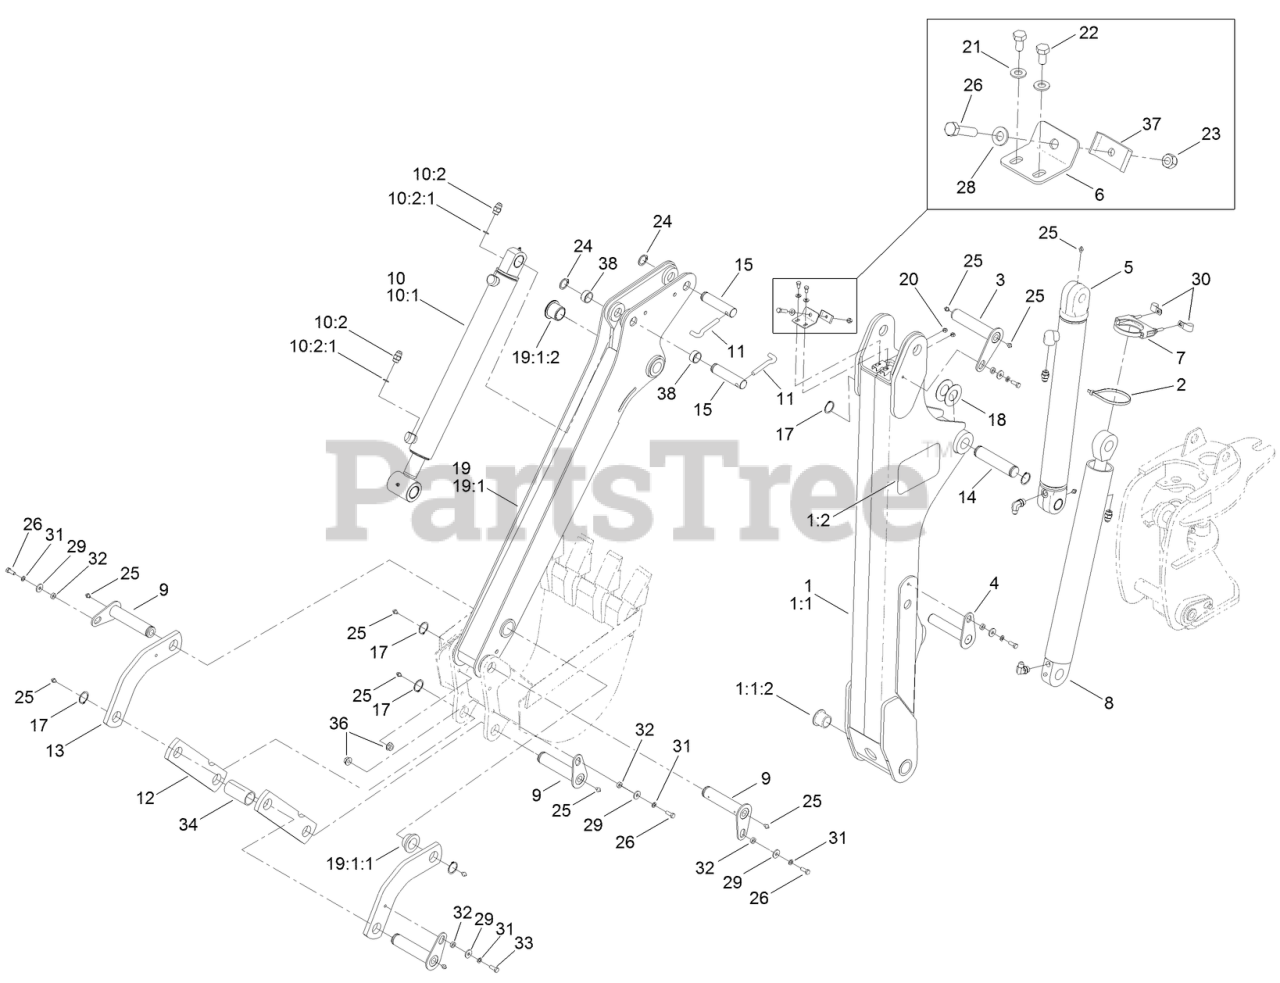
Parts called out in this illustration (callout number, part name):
1	BOOM ASM
1:1	BOOM
1:1:2	BUSHING-PIVOT, BOOM
2	TIE-CABLE
3	PIN-RETAINING
4	PIN-DIPPER CYLINDER TO BOOM
5	HYD CYLINDER ASM (DIPPER)
8	HYD CYLINDER ASM
10	CYLINDER ASM
10:1	HYD CYLINDER ASM (BUCKET)
10:2	FITTING-STRAIGHT
10:2:1	O-RING
11	PIN-RETAINER
12	LINK-STRAIGHT
13	LINK-CURVED
19	DIPPER ASM
19:1	DIPPER
19:1:1	BUSHING-PIVOT, BUCKET
19:1:2	BUSHING
20	NUT-SQUARE
21	WASHER-PLAIN
22	SCREW-HH
23	NUT-HEX
24	RING-RETAINING, EXTERNAL
25	FITTING-GREASE
26	SCREW-HH
28	WASHER-FLAT
29	WASHER-HARDENED
30	CLAMP-R
31	WASHER-LOCK
33	SCREW-HH
34	SPACER-Bucket Links
36	NUT-HF, NI
37	CLAMP-TUBE
38	BUSHING
